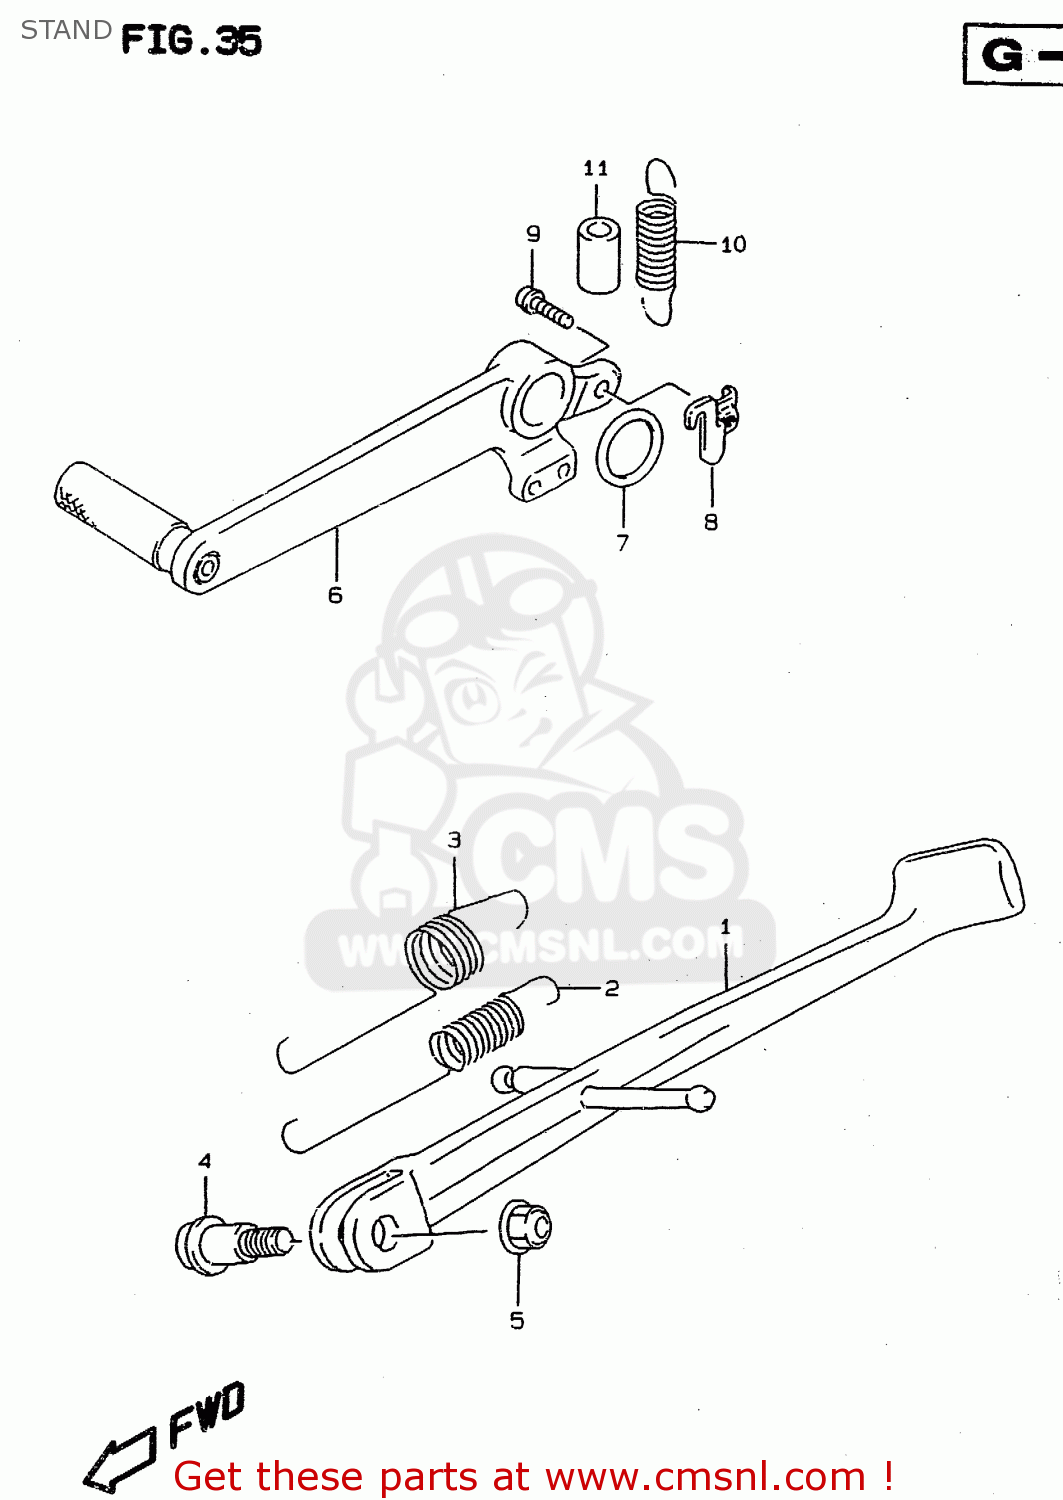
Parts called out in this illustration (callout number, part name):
1	STAND,PROP
2	SPRING
3	SPRING
4	BOLT(10X34)
5	NUT
6	PEDAL,BRAKE
7	WASHER(18X24X1)
8	BRACKET,STOP LAMP SWITCH SPR
9	BOLT
10	SPRING
11	TUBE,BRAKE SPRING GUIDE
